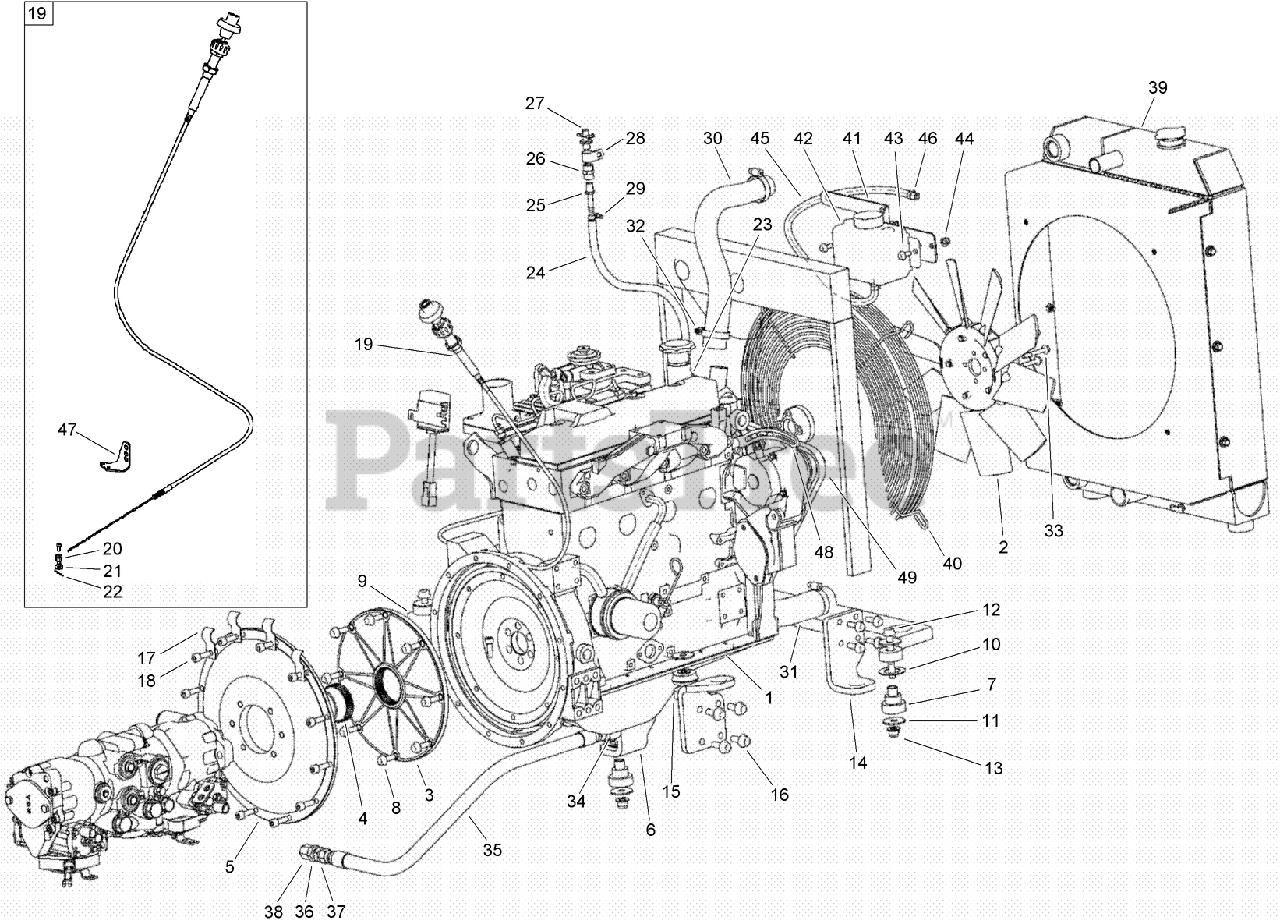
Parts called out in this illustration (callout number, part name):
1	ENGINE-CUMMINS
2	FAN-COOLING
3	FLANGE-Pump
4	HUB-Pump
5	PLATE-Pump Mount
6	PLATE-Engine Mount, Front Left
7	ISOLATOR-MOUNTING, UNIVERSAL
8	SCREW-HH
9	PLATE-Engine Mount, Rear Left
10	SPACER-ISOLATOR
11	WASHER-0.531 x 1.750 x 0.100 in CST ZND
12	SCREW, METRIC FLANGE w/BODY-M12 x 90
13	NUT-HHF, LOCK
14	PLATE-Engine Mount, Front Right
15	PLATE-Engine Mount, Rear Right
16	SCREW, METRIC FLANGE w/BODY-M12 x 30
17	CLIP-Harness Support
18	SCREW-HSH
19	CABLE-THROTTLE
21	WASHER-FLAT
22	PIN-Cotter 0.062 x 0.75 in ZN
23	STEM-STRAIGHT, BEAD
24	HOSE-Vent
25	STEM-STRAIGHT, BEAD
26	COUPLING-PIPE (NPTF)
27	VALVE-SHUTOFF
28	CLAMP-Insul 19.0 mm 3/8 in Bolt ZND
29	CLAMP-Hose Type M #08
30	HOSE-RADIATOR, UPPER
31	HOSE-Lower Radiator
32	CLAMP-Hose Type F #32
33	SCREW-FLANGE
35	HOSE-Oil Drain
36	UNION-BULKHEAD
37	NUT-LOCK, BULKHEAD
38	FITTING-CAP
39	COOLING ASM
40	GUARD-Fan
41	WELDMENT-Overflow Tank Mount
42	TANK-Overflow
43	SCREW, METRIC FLANGE w/BODY - M8 x 20
44	NUT-TORQUE, PREVAILING
45	HOSE-Overflow Out
46	CLAMP-Hose
47	BRACKET-Throttle
48	BRACKET-Alternator
49	BELT-Fan
53	HEATER-Block
